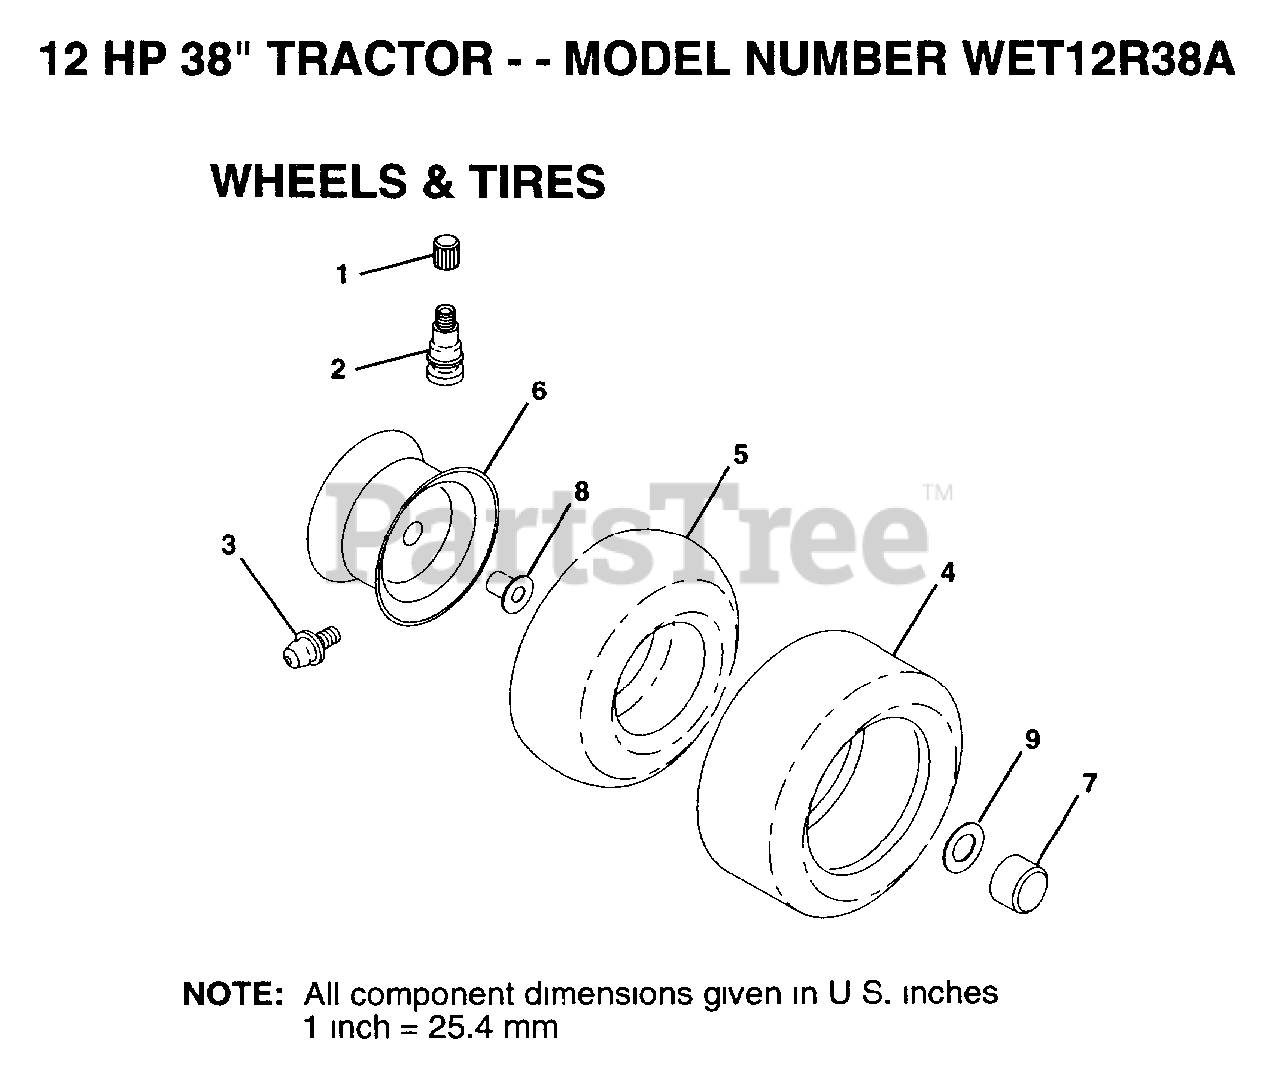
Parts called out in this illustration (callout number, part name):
1	VALVE CAP
2	VALVE STEM LT
3	FITTING LT
5	TUBE.5.3/4.5/6
7	HUB CAP
8	"FLANGE, BEARING"
9	WASHER
